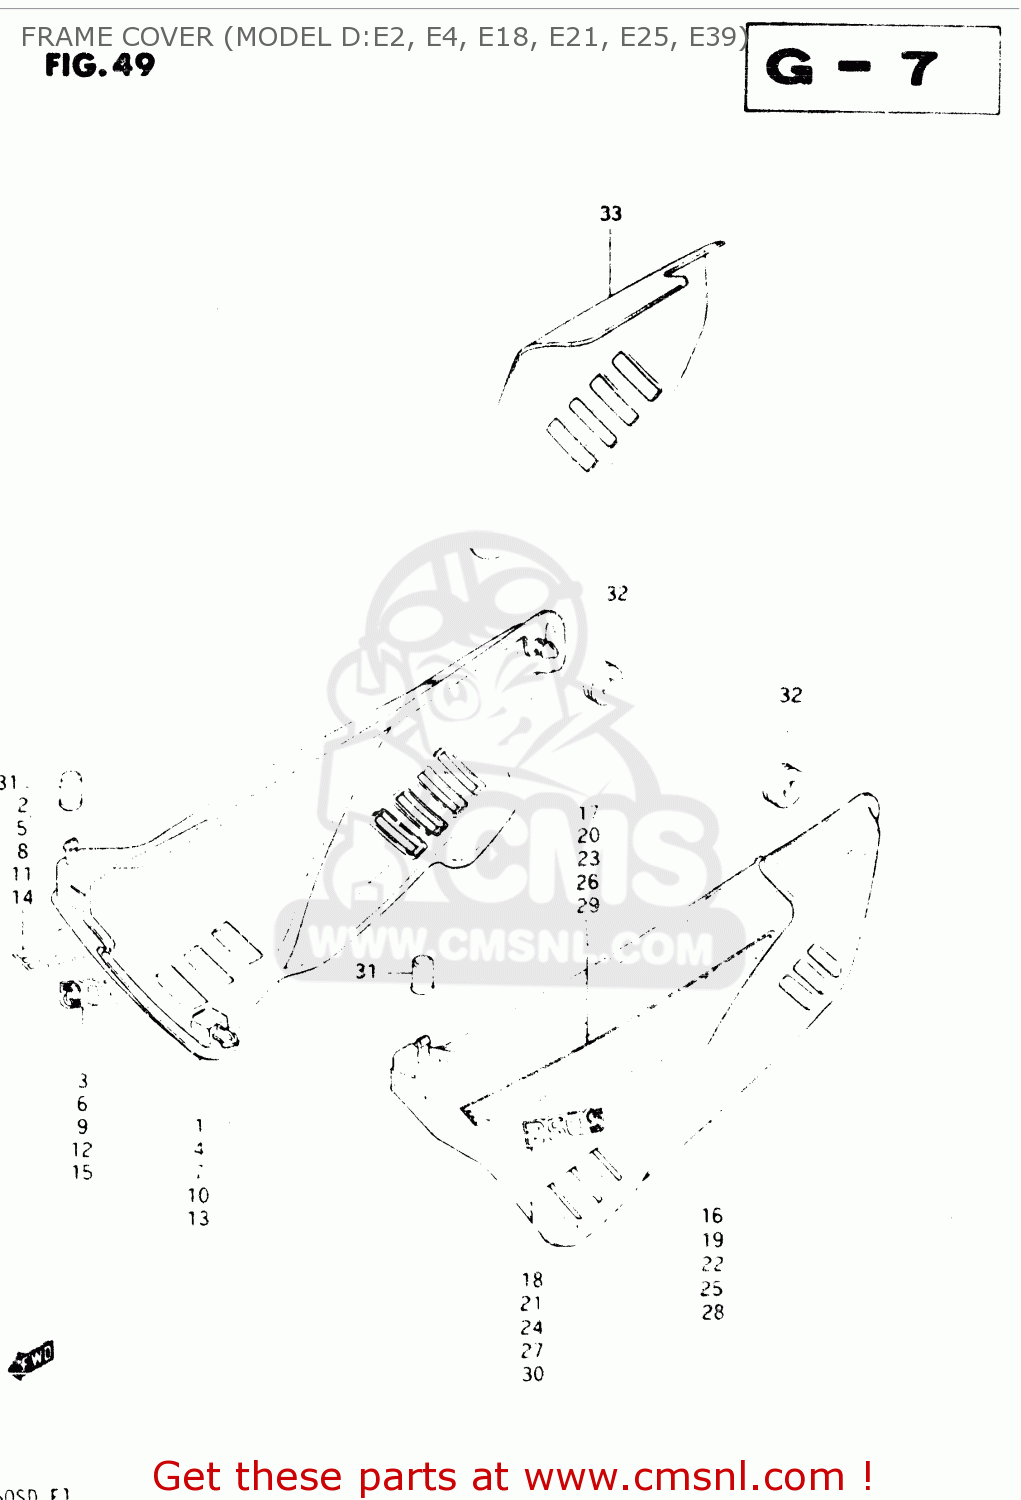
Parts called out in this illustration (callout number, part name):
1	COVER, FRAME RH (BLACK)
2	TAPE SET, FRAME COVER RH
3	EMBLEM, LH
4	COVER, FRAME RH (BLUE)
5	TAPE SET, FRAME COVER RH
6	EMBLEM, LH
7	COVER,FRAME,RIGHT
8	TAPE SET, FRAME COVER RH
9	EMBLEM, LH
10	COVER, FRAME RH (WHITE)
11	TAPE,FRAME COVER,RIGHT
12	EMBLEM
13	COVER, FRAME RH (YELLOW)
14	TAPE SET, FRAME COVER RH
15	EMBLEM
16	COVER, FRAME LH (BLACK)
17	TAPE SET, FRAME COVER LH
18	EMBLEM, LH
19	COVER, FRAME LH (BLUE)
20	TAPE SET, FRAME COVER LH
21	EMBLEM, LH
22	COVER, FRAME LH (RED)
23	TAPE SET, FRAME COVER LH
24	EMBLEM, LH
25	COVER, FRAME, LH
26	TAPE,FRAME COVER,LEFT
27	EMBLEM
28	COVER, FRAME LH (YELLOW)
29	TAPE SET, FRAME COVER LH
30	EMBLEM
31	CUSHION
32	CUSHION
33	HEAT SHIELD,FRAME COVER
